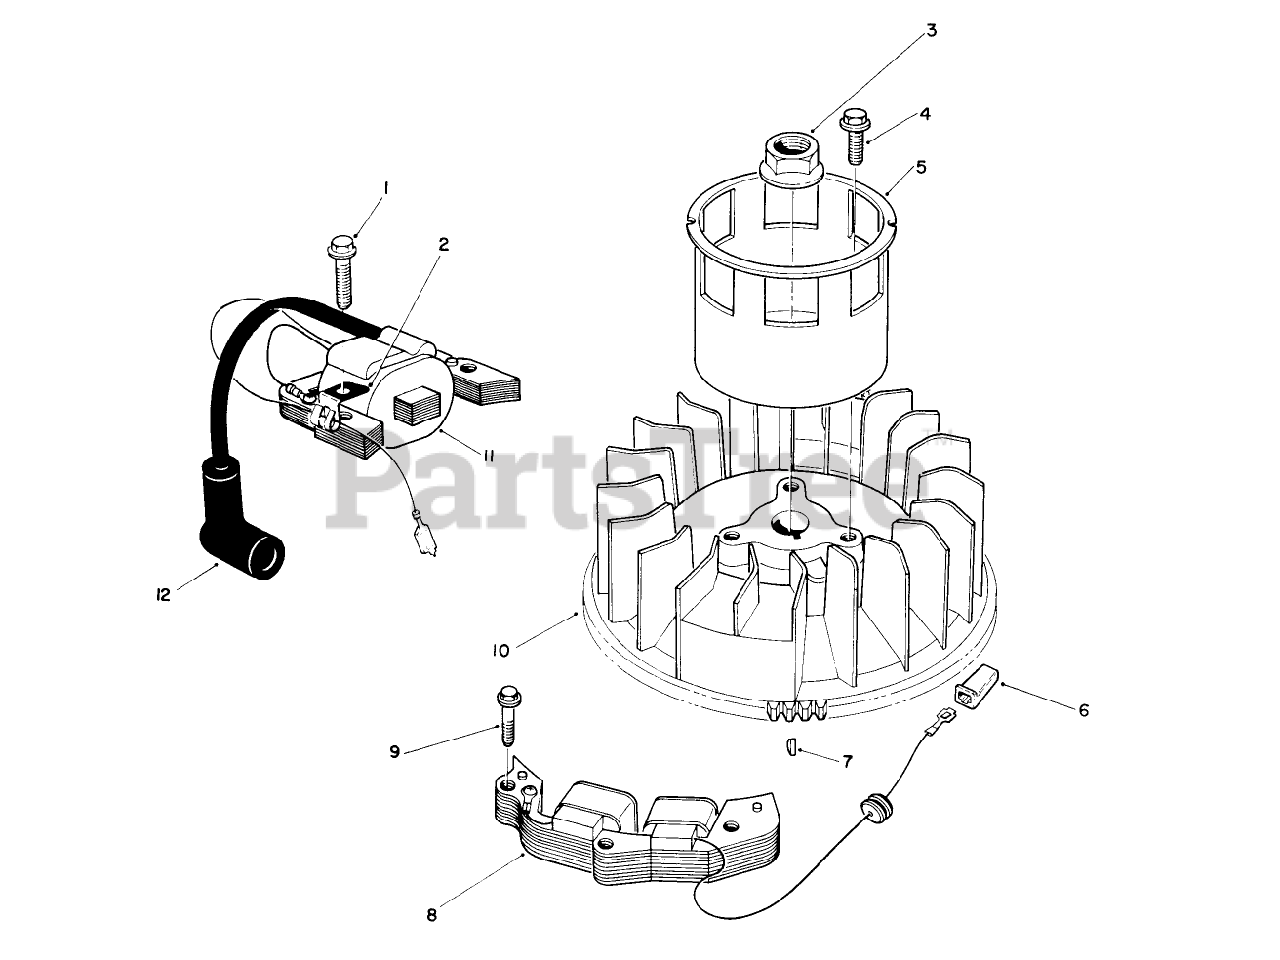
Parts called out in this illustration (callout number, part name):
2	CLAMP
6	CONNECTOR BODY
10	FLYWHEEL
11	COIL ASM
12	COVER
